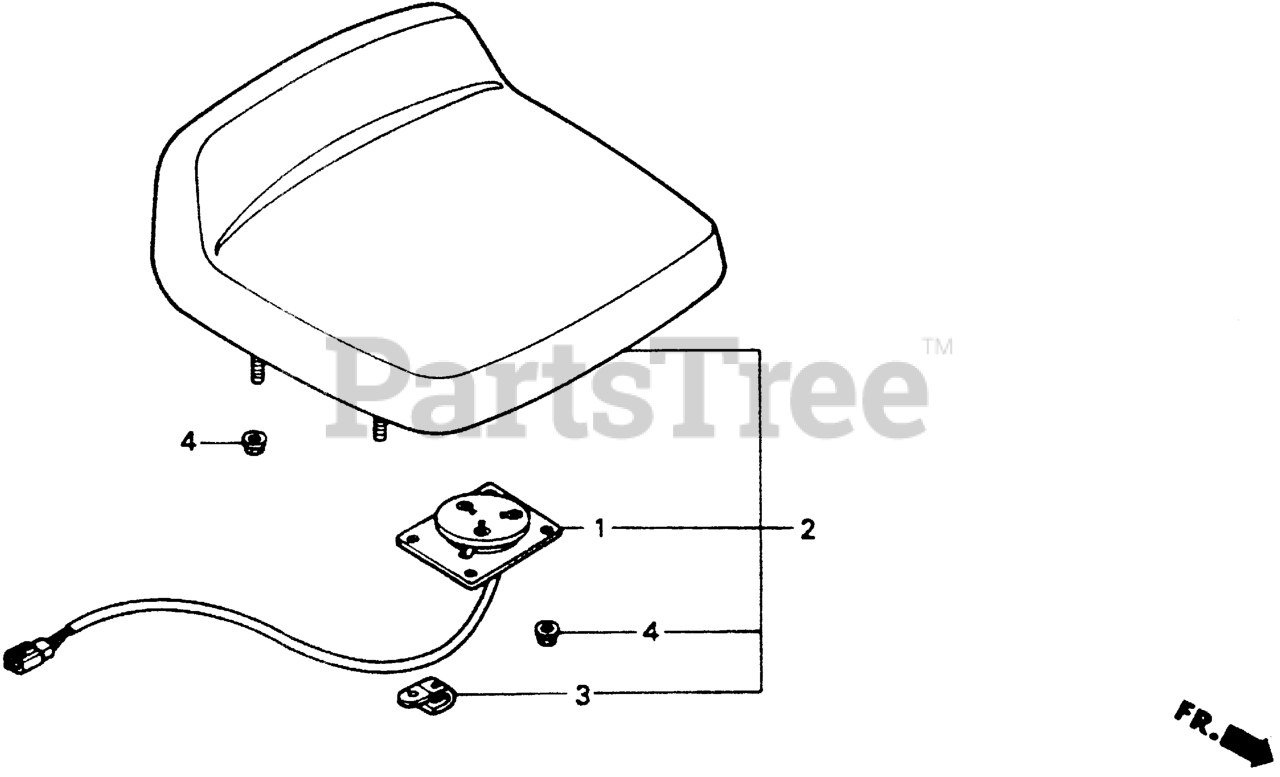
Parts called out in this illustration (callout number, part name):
1	SWITCH ASSY., SEAT
2	SEAT ASSY.
2	SEAT ASSY. (NOT AVAILABLE)
3	CLIP, WIRE HARNESS
4	NUT, FLANGE (6MM)
